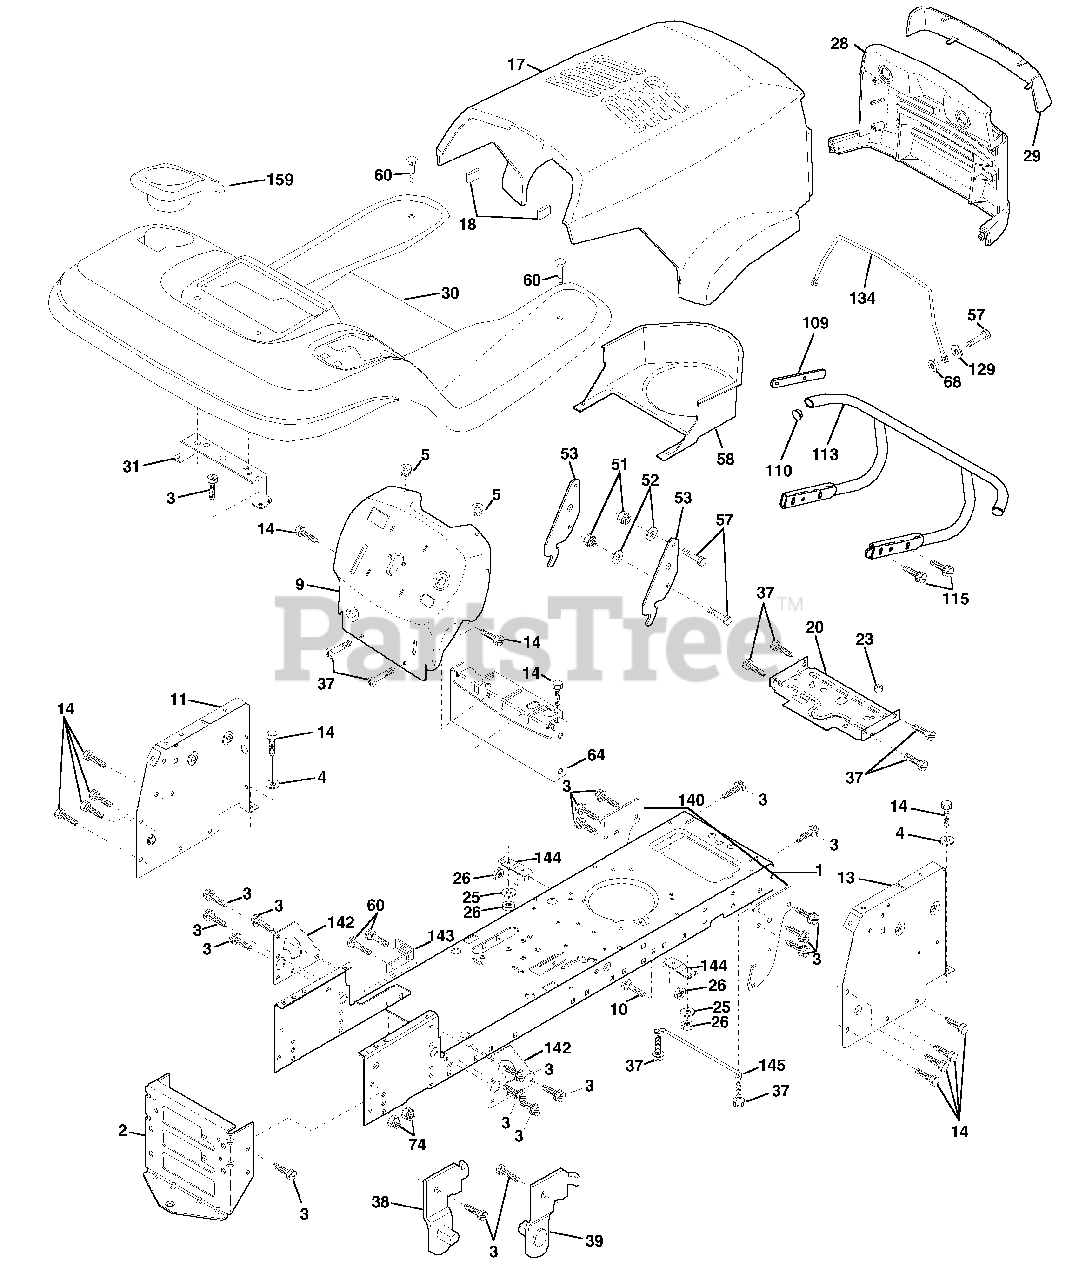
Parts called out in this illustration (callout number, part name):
1	Chassis
2	Drawbar, Stretch
3	Screw Thdrol 3/8-16x3/4 Ty-tt
4	Washer 13/32 x 3/4 x 16 Ga.
5	Bumper Hood/Dash
9	Dash Slkscr
10	Bolt Carriage 3/8-16 x 1
11	Panel Dash Lh
13	Panel Dash Rh
14	Screw Thdrol 3/8-16x1/2 Ty-tt
17	Hood LT/PL Husqvarna
18	Bumper, Hood
20	Plate Mtg Battery Fuel Tank Fr
25	Washer 13/32 X 13/16 X 12 Ga
26	Nut Lock Hex W/Ins 3/8-16 Unc
28	Grille LT/PL Husqvarna
29	Lens LT/PL Husqvarna
30	Fender Footrest STLT Pnt
31	Bracket Support Fender
37	Screw Thdrol 6/16-18 x 1/2 TYT
38	Bracket, Asm. Pivot, L.H., Mower Rear
39	Bracket, Asm. Pivot, R.H., Mower Rear
51	Nut Lock Hex W/Ins 1/4-20
52	Washer 9/32 x 7/8 x 16 Ga.
53	Bracket Pnt. Pick off LT/PL Husqvarna
57	Bolt Hex 1/4-20 x 3/4
58	Air Duct Engine CV18
60	Bolt Rdhd Sqnk 3/8-16unc x 3/4
64	Dash Lower STLT
68	Nut Keps Hex 1/4-20 Unc
74	Nut Crownlock 3/8-16 UNC
109	Bracket Extension Bumper
110	Plug Plastic
113	Bumper Asm.
115	Screw Thdrol 3/8-16 x 1/4 TYTT
129	Washer 9/32 x 5/8 x 16 Ga.
134	Rod Support Hood LT/PL Husq.
140	Bracket Chassis Front 7 Ga.
142	Plate Reinforcement STLT
143	Bracket Swaybar Chassis
144	Bracket Pnt Footrest STLT
145	Rod Pivot Chassis/Hood
159	Cup Holder STLT Grey
